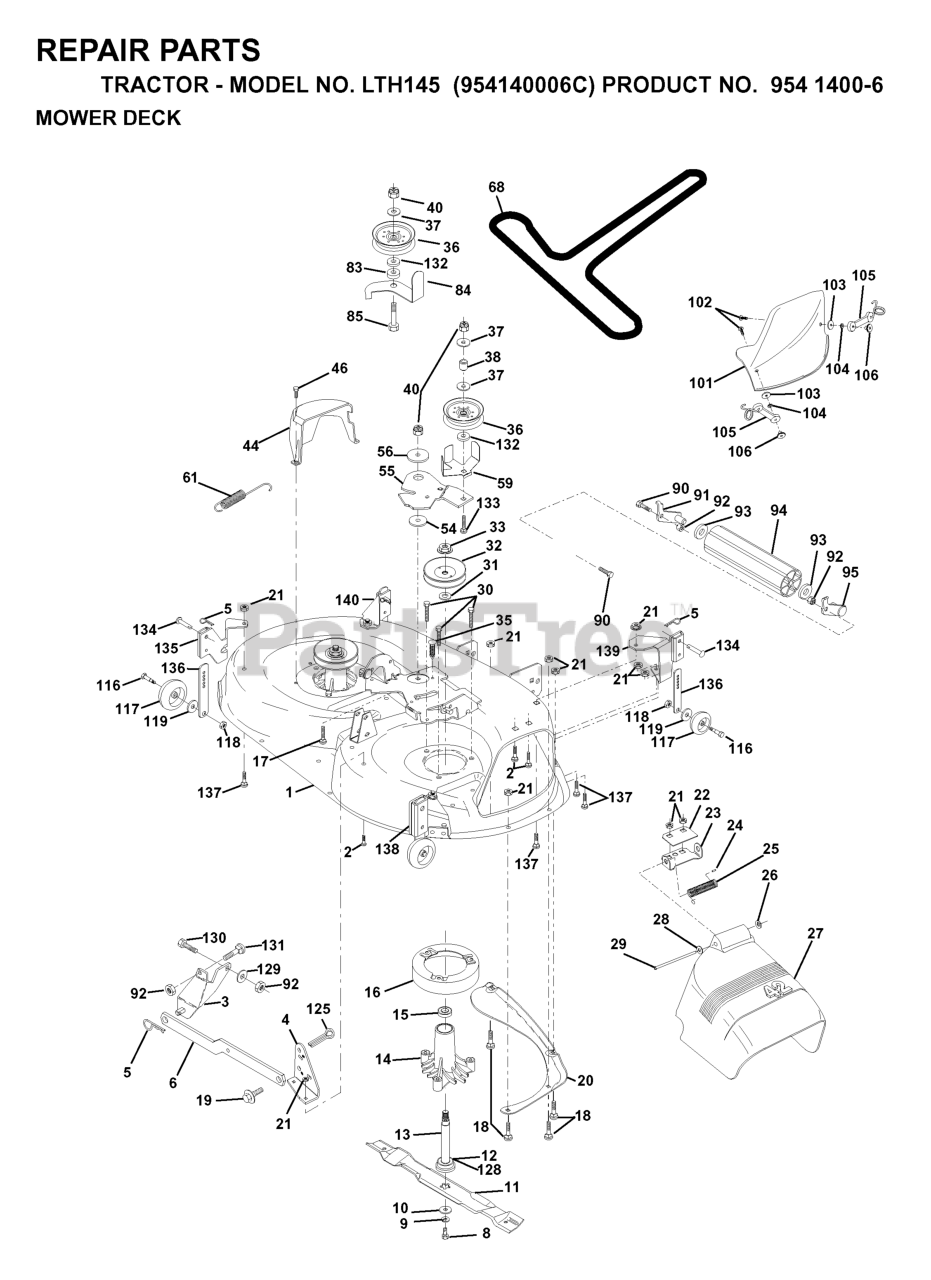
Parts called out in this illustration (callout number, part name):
2	RP BOLT 5/16-18 X3/4 ZN/YEL GR
3	BRKT ASM SWAY BAR
4	BRKT DECK SW BAR
5	RETAINER-SPRNG RB
6	REAR SUSP ARM
8	BLADE BOLT
9	LOCKWASHER
10	WASHER.BLADE
11	BLADE.42".MULCH
12	BEARING.BALL.#6204.(MANDREL)
13	SHAFT ASM VENT
14	HOUSING.MANDREL.VENTED (MACHD)
16	STRIPPER
17	BOLT CARRIAGE
18	BOLT
19	BOLT SHD 5/16-18
20	BAFFLE.VORTEX
21	LOCKNUT
22	STIFFENER BRACKET
23	DEFLECTOR BRACKET
24	CAP-SLEEVE LT
25	SPRING TORSION
26	NUT PUSH M
27	SHIELD.DEFLECTOR.MOWER.42".BLK
28	Washer 11/32 x 5/8 x 16 Ga SD
29	ROD.HINGE
30	SCREW THDROL ROLLING WASHER HD
31	WASHER
32	PULLEY/MANDREL
33	NUT
35	FASTENER.XMAS.TREE
36	FLAT IDLER PULLEY
37	WASHER
38	IDLER SPRING SPACER
44	GUARD MANDREL LH BLACK
46	SCREW.1/4-20X5/8
54	HARDENED WASHER
55	IDLER ARM
56	SPACER RETAINER
59	GUARD, BELT
61	SPRING EXTENSION
68	BELT V SECONDARY
84	KEEPER.BELT.IDLER
85	BOLT
90	BOLT
91	BRACKET LH (A)
92	NUT
93	Washer 1 17/32 X 7/8 X 16 Ga
94	NOSE ROLLER
95	BRACKET RH (B)
101	COVER MULCH 42"
102	SCREW
104	LOCKWASHER #10
105	LATCH ASSY
106	WELDNUT
116	BOLT, SHOULDER
117	WHEEL GAGE DONUT
118	LOCKNUT
119	WASHER.5/16.FLAT.STE.STD.
125	Pin Cotter 1/4 x 1 Plated
128	WASHER FELT
129	WASHER
131	BOLT D
132	Washer 13/32 x 1-3/8 x 13 Ga.
134	RIVET.PIN.HEAD.YELLOW.
135	BRACKET ASSY
137	BOLT.CARR.5/16-18X5/8.SHORT
138	GAUGE WHEEL BRACKET ASSY
139	BRACKET.WHEEL.GAUGE.FRONT.42
140	BRKT.ASM.WHL.GA.FRONT.LH
